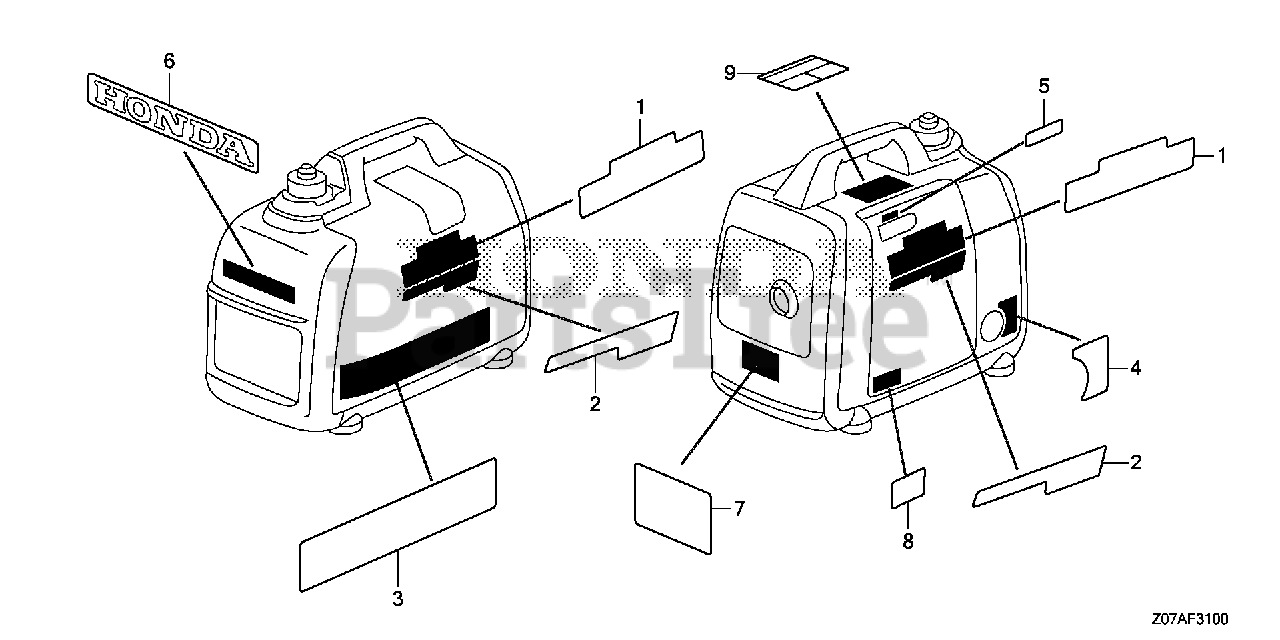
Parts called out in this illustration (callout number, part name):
1	MARK, EMBLEM (EB2000I)
2	MARK, STRIPE
3	MARK, CAUTION
4	MARK, ENGINE SWITCH
5	MARK, CHOKE
6	MARK, HONDA
7	MARK, EX. WARNING (E)
8	MARK, OIL CAUTION
9	MARK, CPSC (CO CAUTION)
